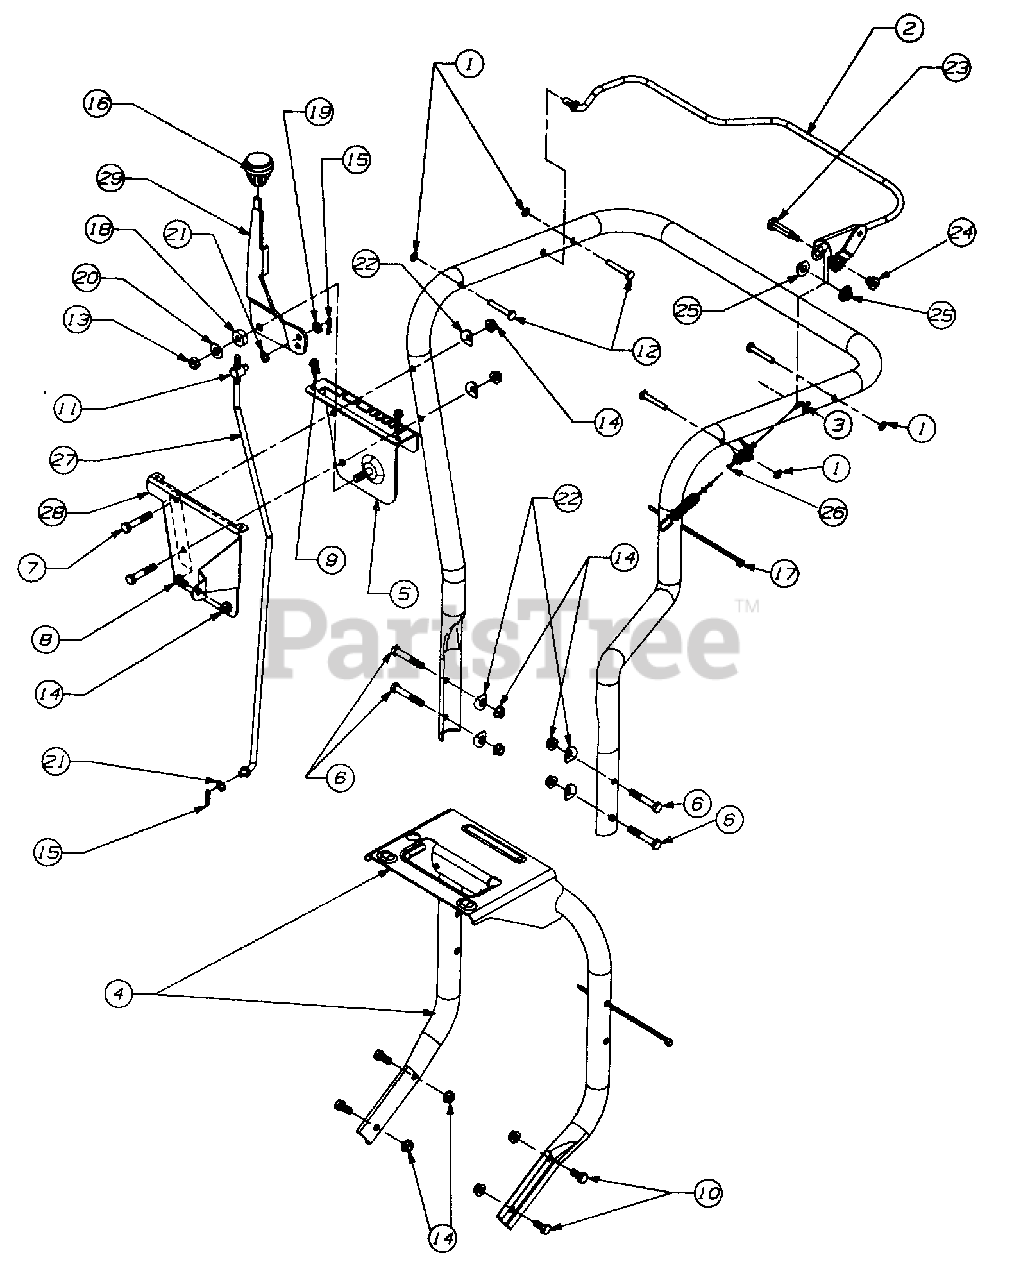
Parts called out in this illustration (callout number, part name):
1	PUSHNUT
7	SCREW - HEX
8	SCREW - HEX
9	SCREW - HEX
10	SCREW - HEX
11	FERRULE
12	PIN - STUD
13	NUT - HEX LOCK
14	NUT - HEX LOCK
15	PIN - COTTER
16	KNOB - SHIFT
17	CABLE TIE
18	WASHER -RUBBER
19	WASHER - FLAT
20	WASHER - FLAT
21	WASHER - SPRING
22	WASHER - SADDLE
23	SCREW - SHOULDER
24	NUT - SHOULDER
25	BEARING - FLANGE PLASTIC
26	CABLE - CLUTCH
27	ROD - SHIFT
